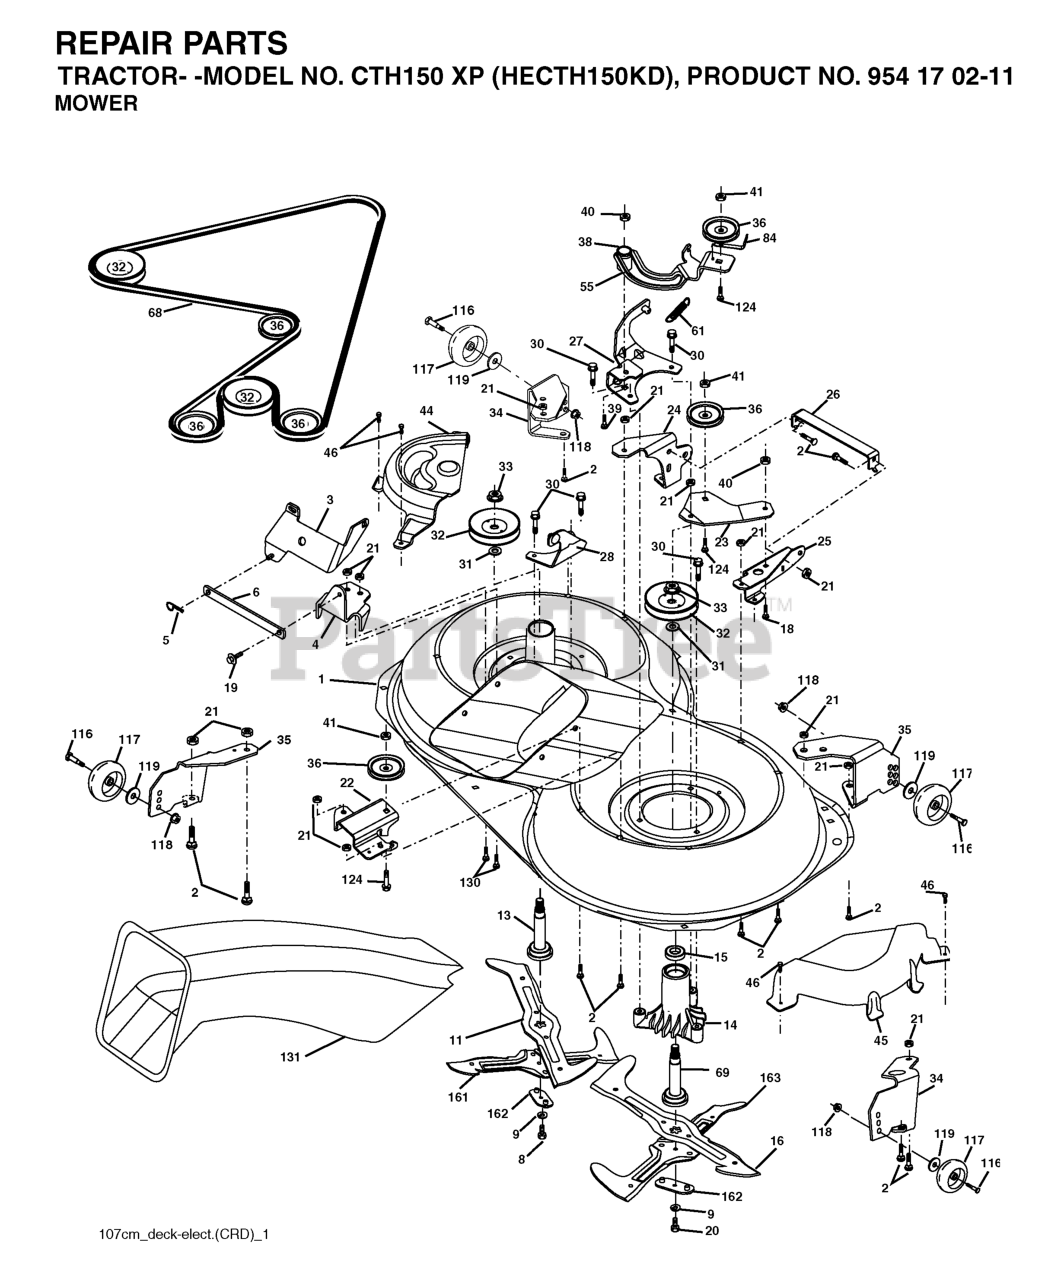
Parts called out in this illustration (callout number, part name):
1	Housing Asm. Mower 107 CRD
2	RP BOLT 5/16-18 X3/4 ZN/YEL GR
5	RETAINER-SPRNG RB
6	BAR.SWAY.92.CRD
8	BOLT.3/8-24X1.25 GR8
9	LOCKWASHER
11	BLADE.3N1.LH.CRD
13	SHAFT ASM VENT
14	HOUSING.MANDREL.VENTED (MACHD)
16	BLADE.3N1.RH.CRD
18	BOLT
19	BOLT SHD 5/16-18
20	BOLT.3/8-24X1.25GR8. LHTHRD
21	LOCKNUT
22	BRACKET.IDLER.RR.107.CRD
25	BRACKET.SUSPENSION.RF.107.CRD
26	BRACE.SUPT.SUSP.FRT.CRD
28	BRACKET
30	SCREW, WASHER HEAD
31	WASHER.SPACER.MANDREL
33	NUT, FLG TOPLOCK 9/16"
36	PULLEY.IDLER.4.25
40	NUT LOCK FLG 3/8-16 UNC
45	COVER.MANDREL.RH.CRD
46	SCREW.1/4-20X5/8
55	ARM.IDLER.107.CRD
68	HEX-BELT 107 MOWER
69	SHAFT.ASM.W/LWR.BRG.RH.THREAD
84	KEEPER, BELT IDLER
116	SHOULDER BOLT
117	WHEEL GAGE DONUT
118	LOCKNUT
119	WASHER.5/16.FLAT.STE.STD.
124	BOLT.3/8-16X1.50
130	BOLT.CARR.SQNK.5/16-18UNC.X3/4
131	CHUTE BAGGER
163	BLADE.CROSS.RH.CRD.107
164	BRNG T
